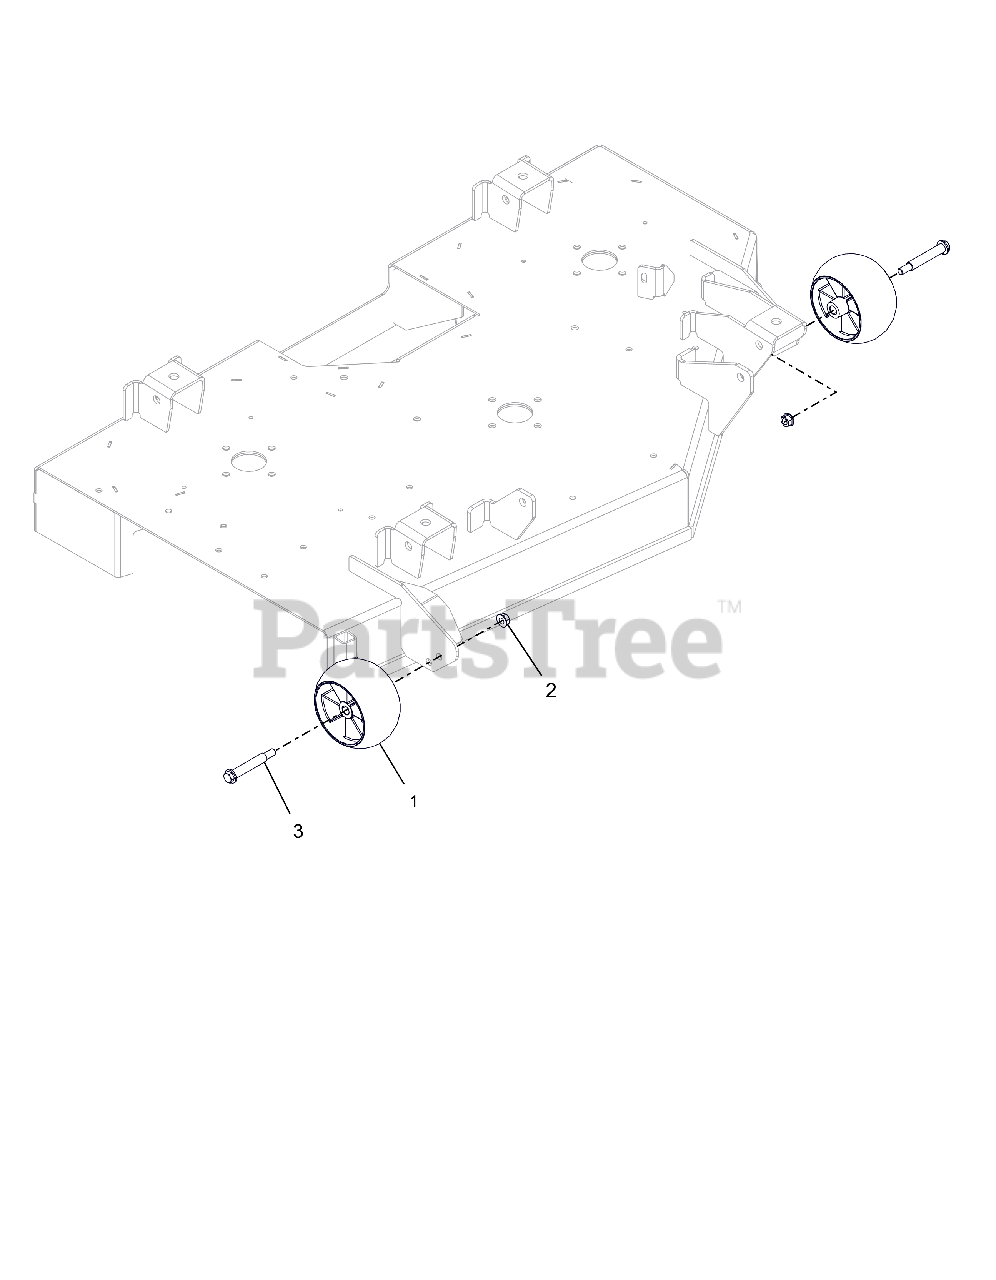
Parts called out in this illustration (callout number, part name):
1	ANTI-SCALP WHEEL - 5X OS
2	NUT-LK-TOP-FLG .38-16 ZC120
3	BLT-SHLDR .38-16X2.50 HWH G5
